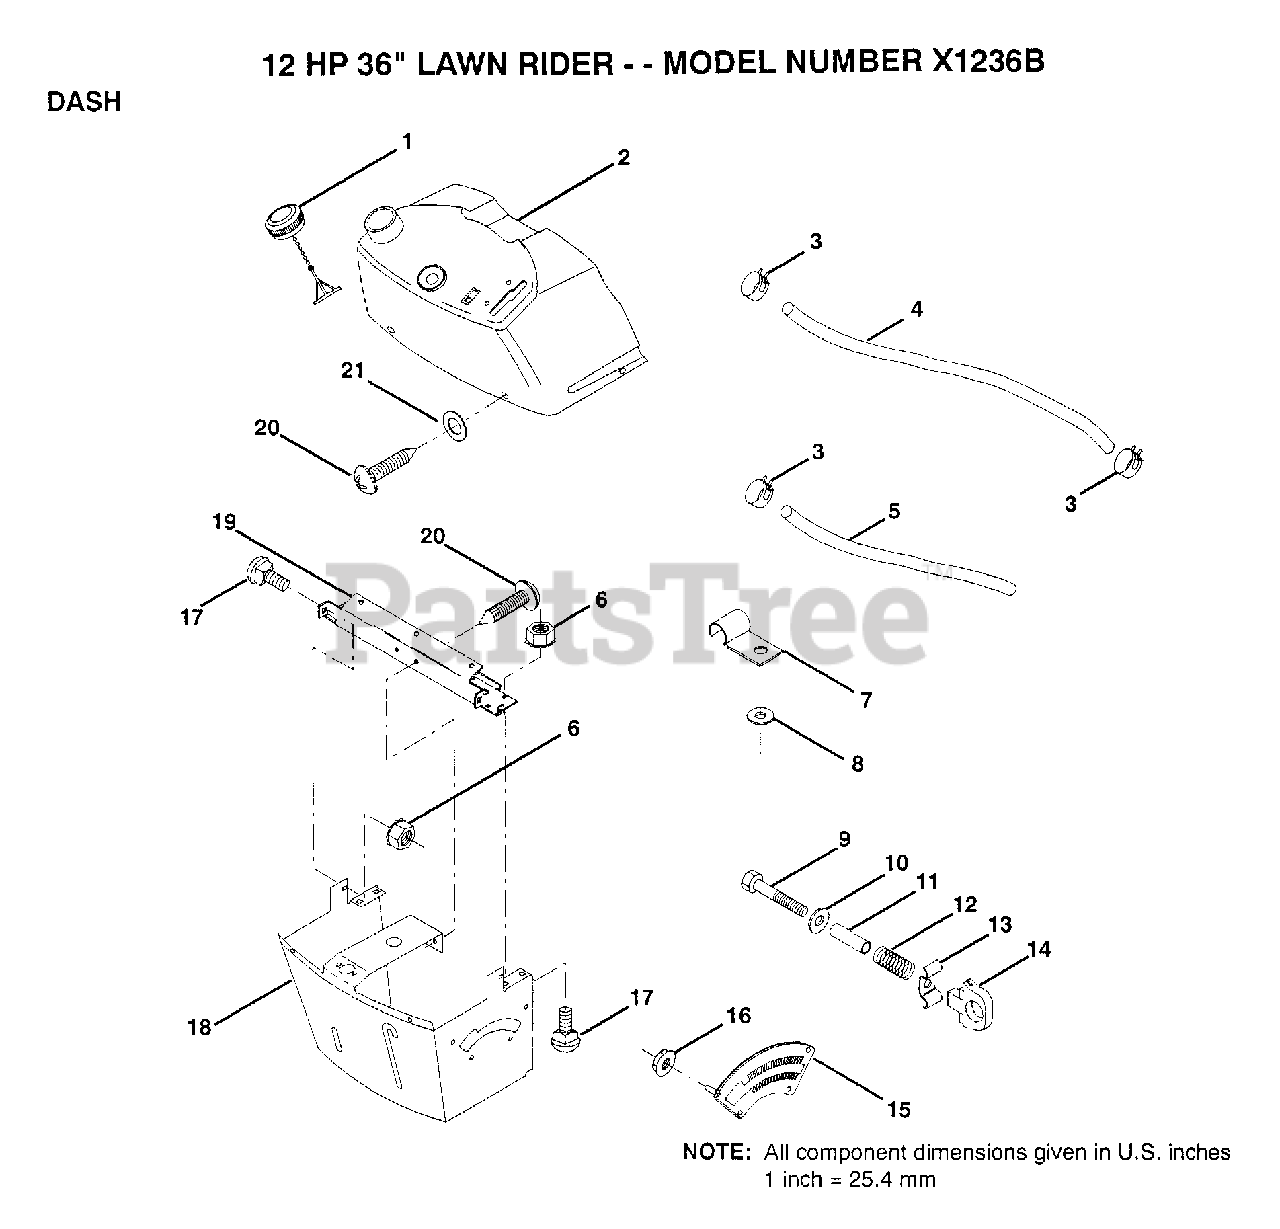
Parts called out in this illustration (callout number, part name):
3	HOSE CLAMP
5	FUEL LINE T
6	NUT
7	CLIP T
8	WASHER PM
9	BOLT
10	WASHER
11	SPACER SPLIT
12	SPRING T
13	HEIGHT ADJ
14	KNOB
15	ADJUSTER QUAD
16	NUT
17	BOLT
18	SUPT ASSY DASH
